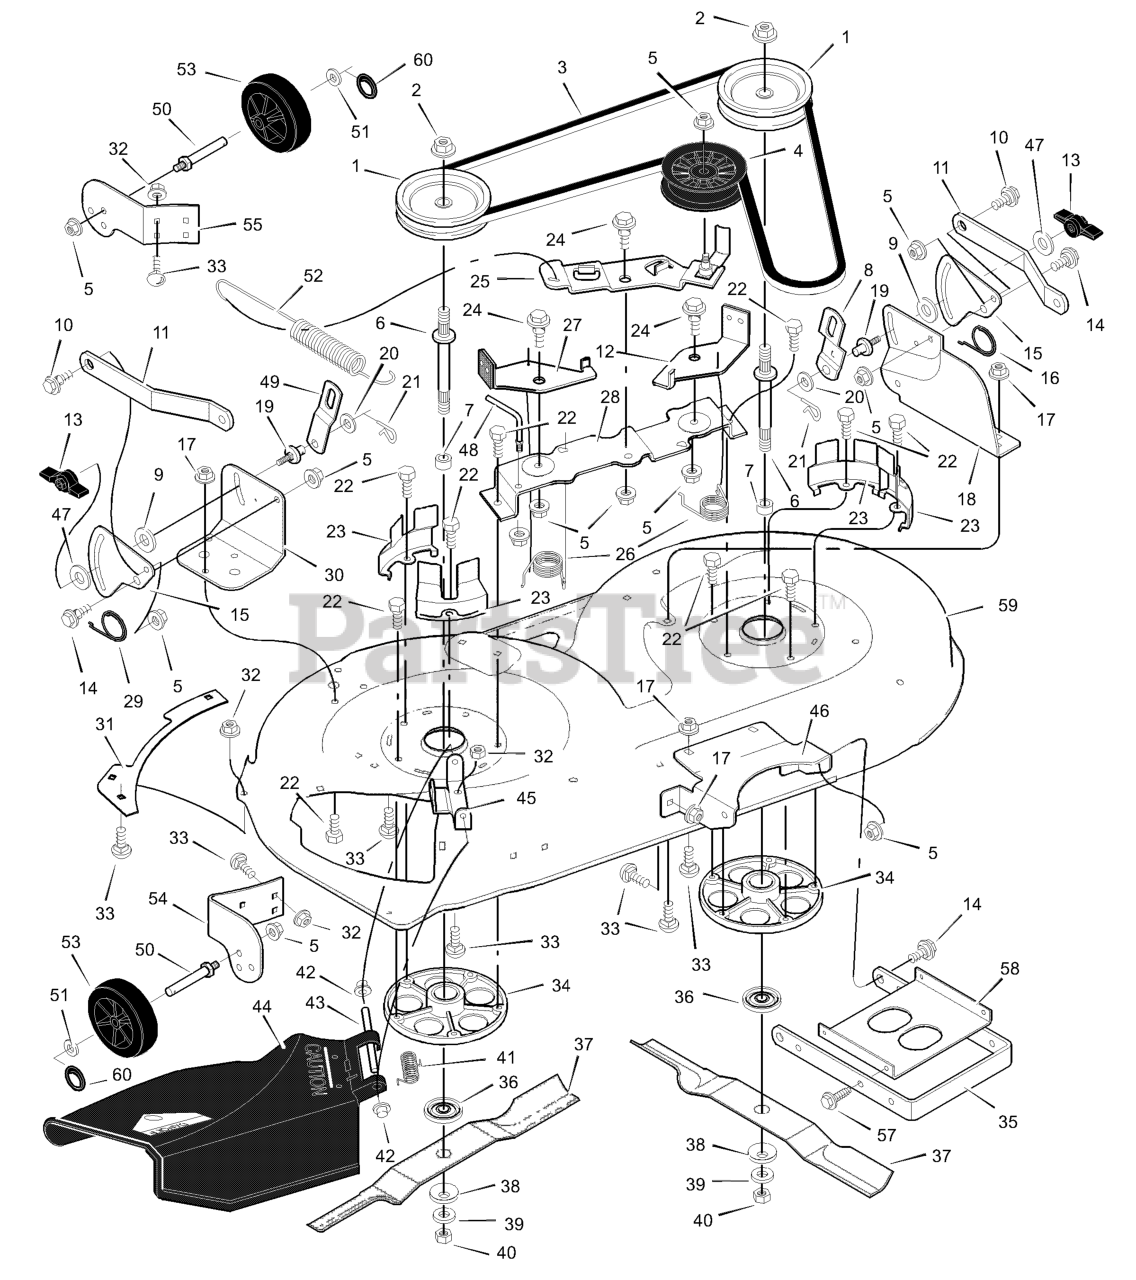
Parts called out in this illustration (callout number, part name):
1	Pulley, Jackshaft
2	Nut, Hex
3	Belt, Mower Drive
4	Pulley, Idler
5	Nut, Flange
6	Jackshaft
8	Link, Left Lift
9	Pad, Friction
10	Bolt, Shoulder
11	Bracket, Suspension
12	Pad Assembly, Left Brake
13	Knob
14	Bolt, Shoulder
15	Plate, Suspension
17	Nut, Flange
18	Bracket, Suspension
19	Pin, Hanger
21	Pin, Hair
22	Bolt
23	Cover, Pulley
24	Bolt, Shoulder
25	Arm, Idler
27	Pad Assembly, Right Brake
28	Bracket, Brake
30	Bracket, Suspension
32	Nut, Flange
33	Bolt, Carriage
34	Mandrell Housing
35	Bracket, Suspension
36	Adapter, Blade
42	Cap, Push On
43	ROD, Deflector
44	Deflector Assembly
45	Bracket, Deflector Hinge
46	Bracket, Front Hanger
48	Guide, Belt
49	Link, Right Lift
50	BOLT, Gauge Wheel
52	Spring, Extension
53	Wheel, Gage
54	Bracket, Right Wheel
55	Bracket, Left Wheel
58	Stiffener
59	Housing, Blade, Complete (NO LONGER AVAILABLE)
59	Housing, Blade (Housing Only)
60	Ring, Locking
